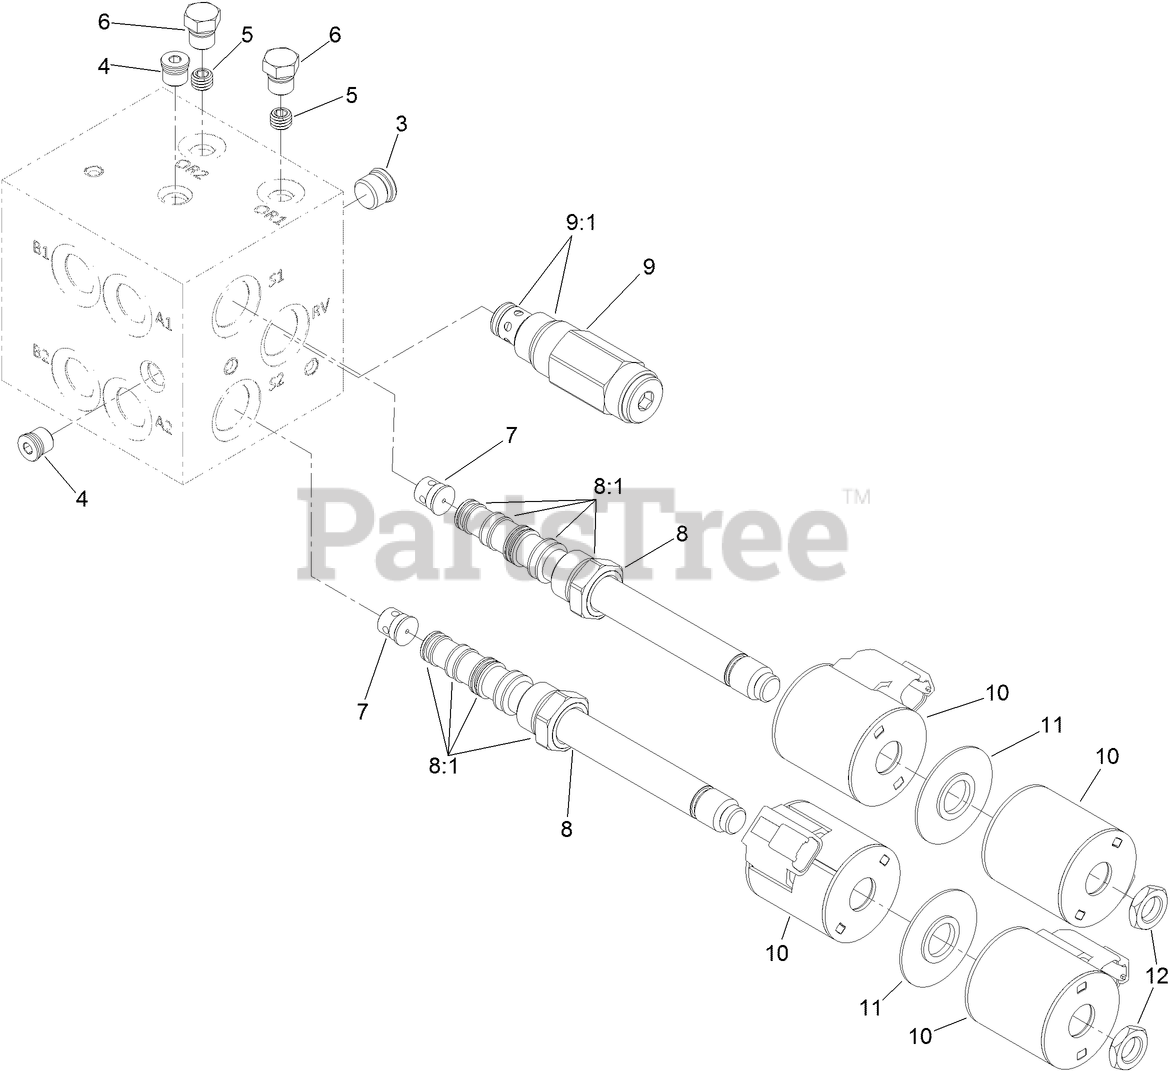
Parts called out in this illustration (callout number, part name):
5	ORIFICE-0.125
7	CHECK VALVE
8	SPOOL ASM
8:1	SEAL KIT
9	VALVE-RELIEF
9:1	SEAL KIT
10	COIL-SOLENOID
11	SUPPORT-TANK
12	NUT-COIL
